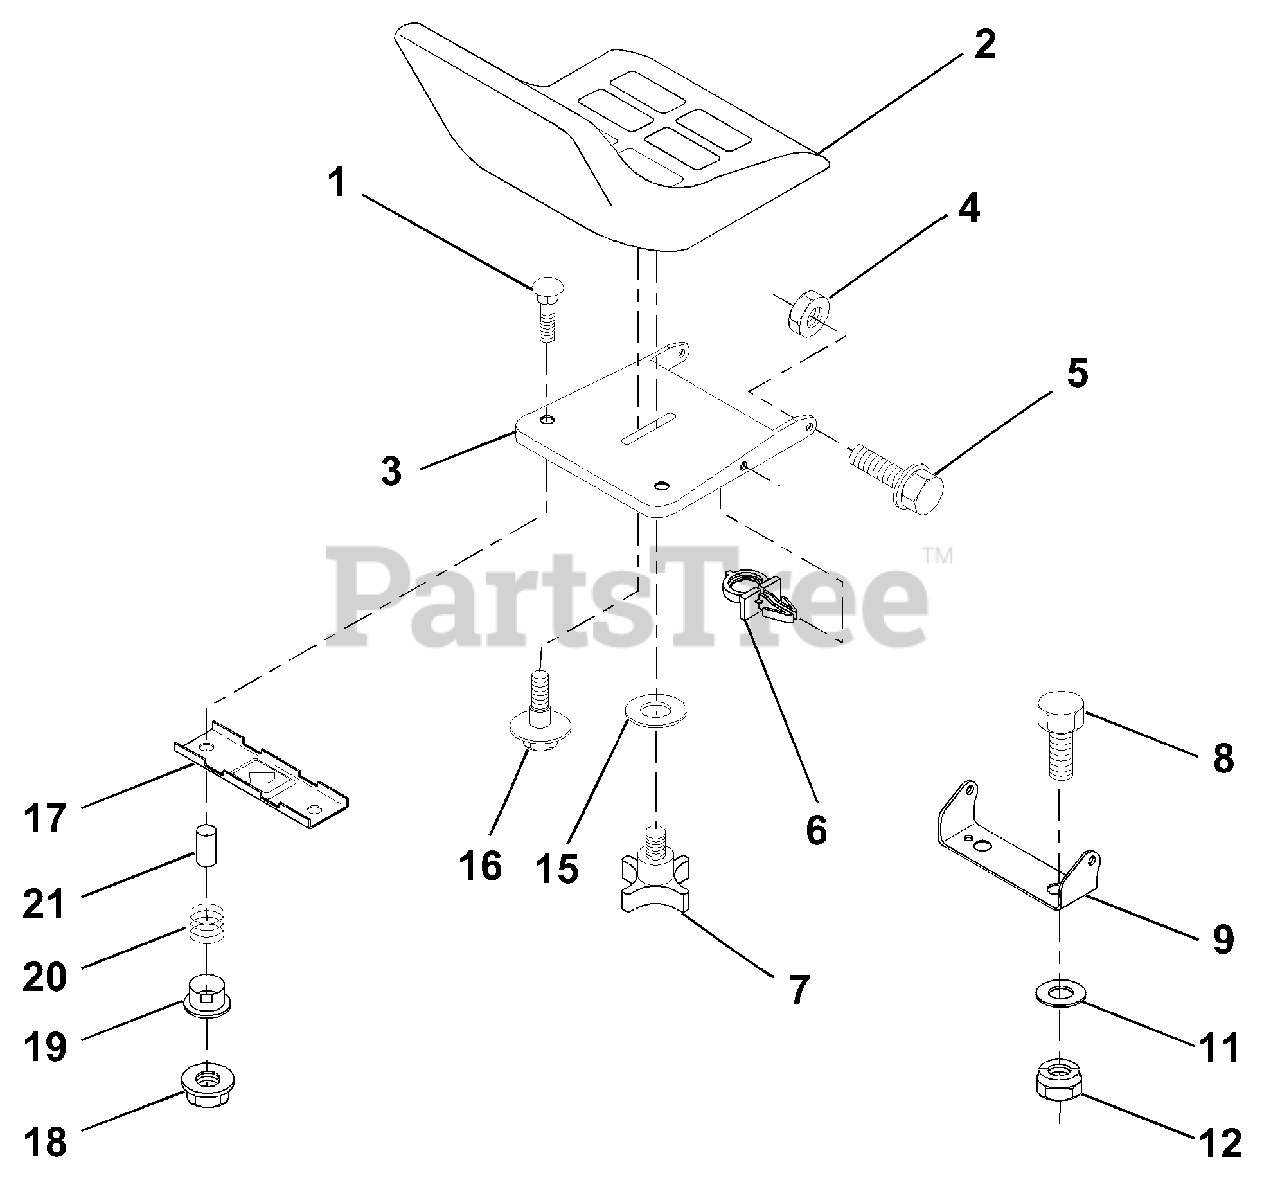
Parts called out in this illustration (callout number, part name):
1	Bolt, Carriage 1/4-20 x 1-3/8
2	Seat
3	Pan, Seat
4	Nut, Hex, Lock w/wsh 5/16-18
5	Bolt, Shoulder 5/16-18 UNC
6	Clip, Push-in
7	Knob, Seat
8	Bolt, Hex, Fin. 3/8-16 UNC x 1
9	Bracket, Pivot, Seat
11	Washer 12/32 x 2 x 10 Gauge
12	Nut, Hex, Lock Hex w/wsh 3/8-16
15	Washer 17/32 x 1-3/16 x 12 Gauge
16	Bolt, Shoulder
17	Bracket, Switch Mounting
18	Nut, Hex, Large, Flange Lock
19	Bushing, Snap
20	Spring, Compression
21	Spacer, Split, Large .28 Id. x .96
